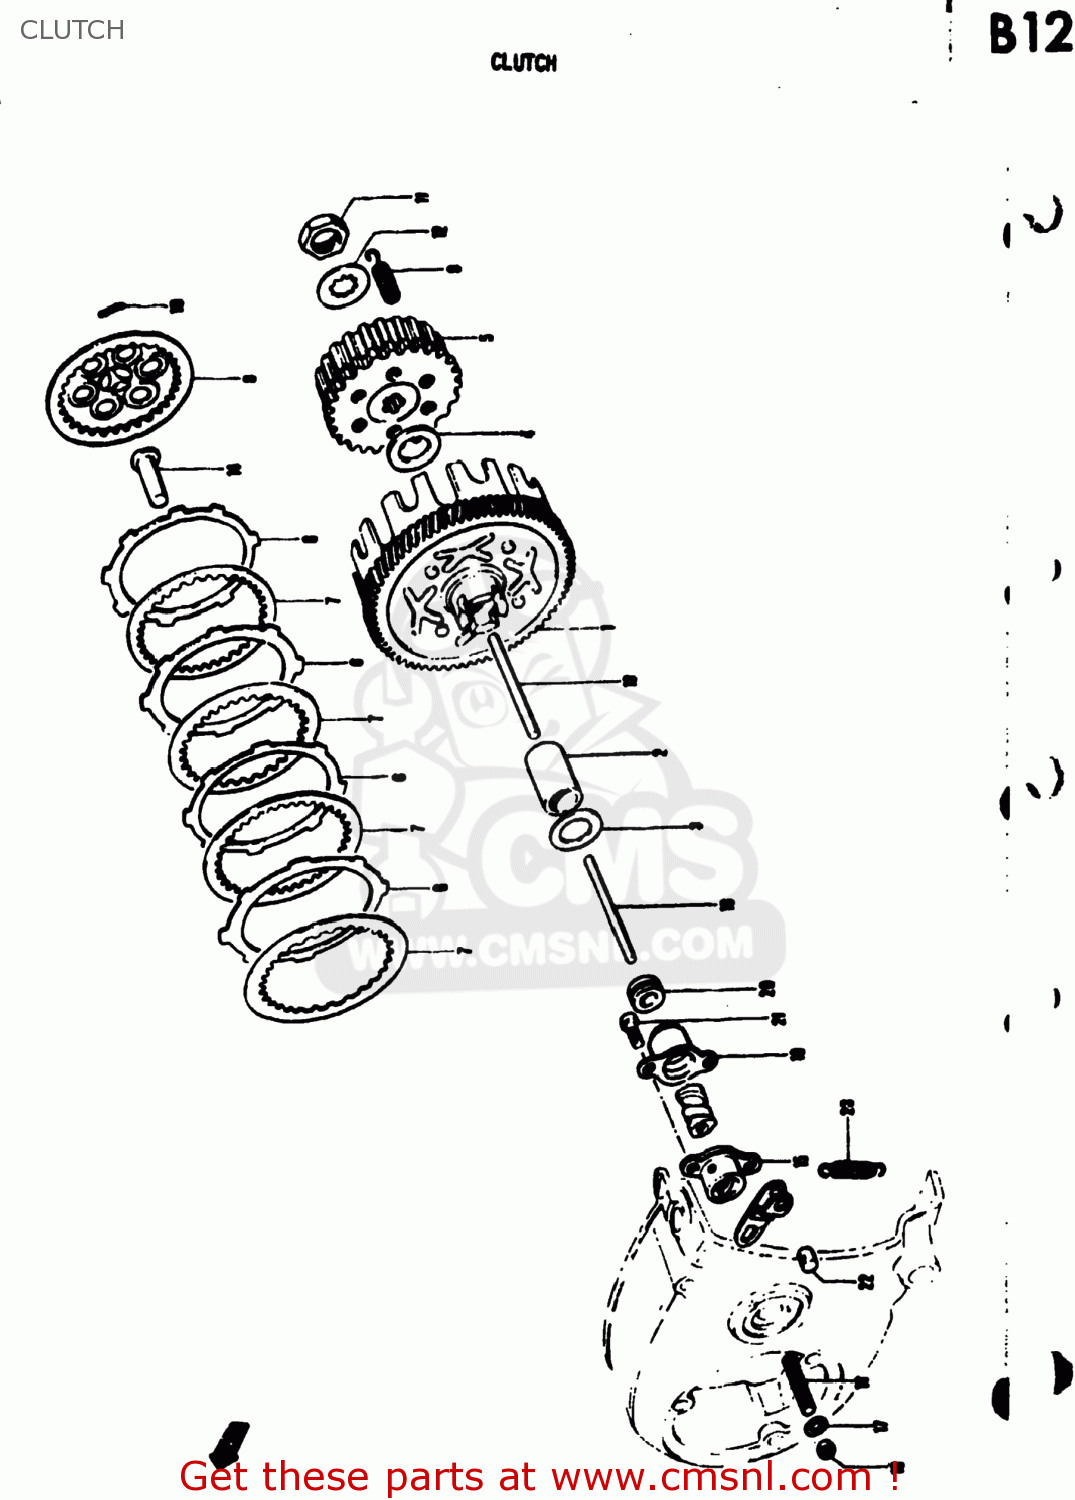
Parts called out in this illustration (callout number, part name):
1	GEAR ASSEMBLY,PRIMARY DRIVE
2	SPACER (17X21X33.5)
3	WASHER,THRUST
4	WASHER
5	HUB,CLUTCH SLEEVE
6	PLATE,CLUTCH DRIVE (MCA)
7	PLATE,CLUTCH DRIVEN (NAS)
8	PLATE,CLUTCH PRESSURE
9	SPRING
10	PIN(2.5X19.8)
11	NUT
12	WASHER,LOCK
13	ROD,CLUTCH PUSH
14	PIECE,CLUTCH PUSH
15	SCREW ASSEMBLY,CLUTCH RELEASE
16	SCREW
17	WASHER(6.5X16X1.2)
18	NUT
19	COVER,CLUTCH RELEASE SCREW
20	SEAL,DUST(5.3X13X5)
21	SCREW
22	PIECE,RELEASE ARM END
23	SPRING
